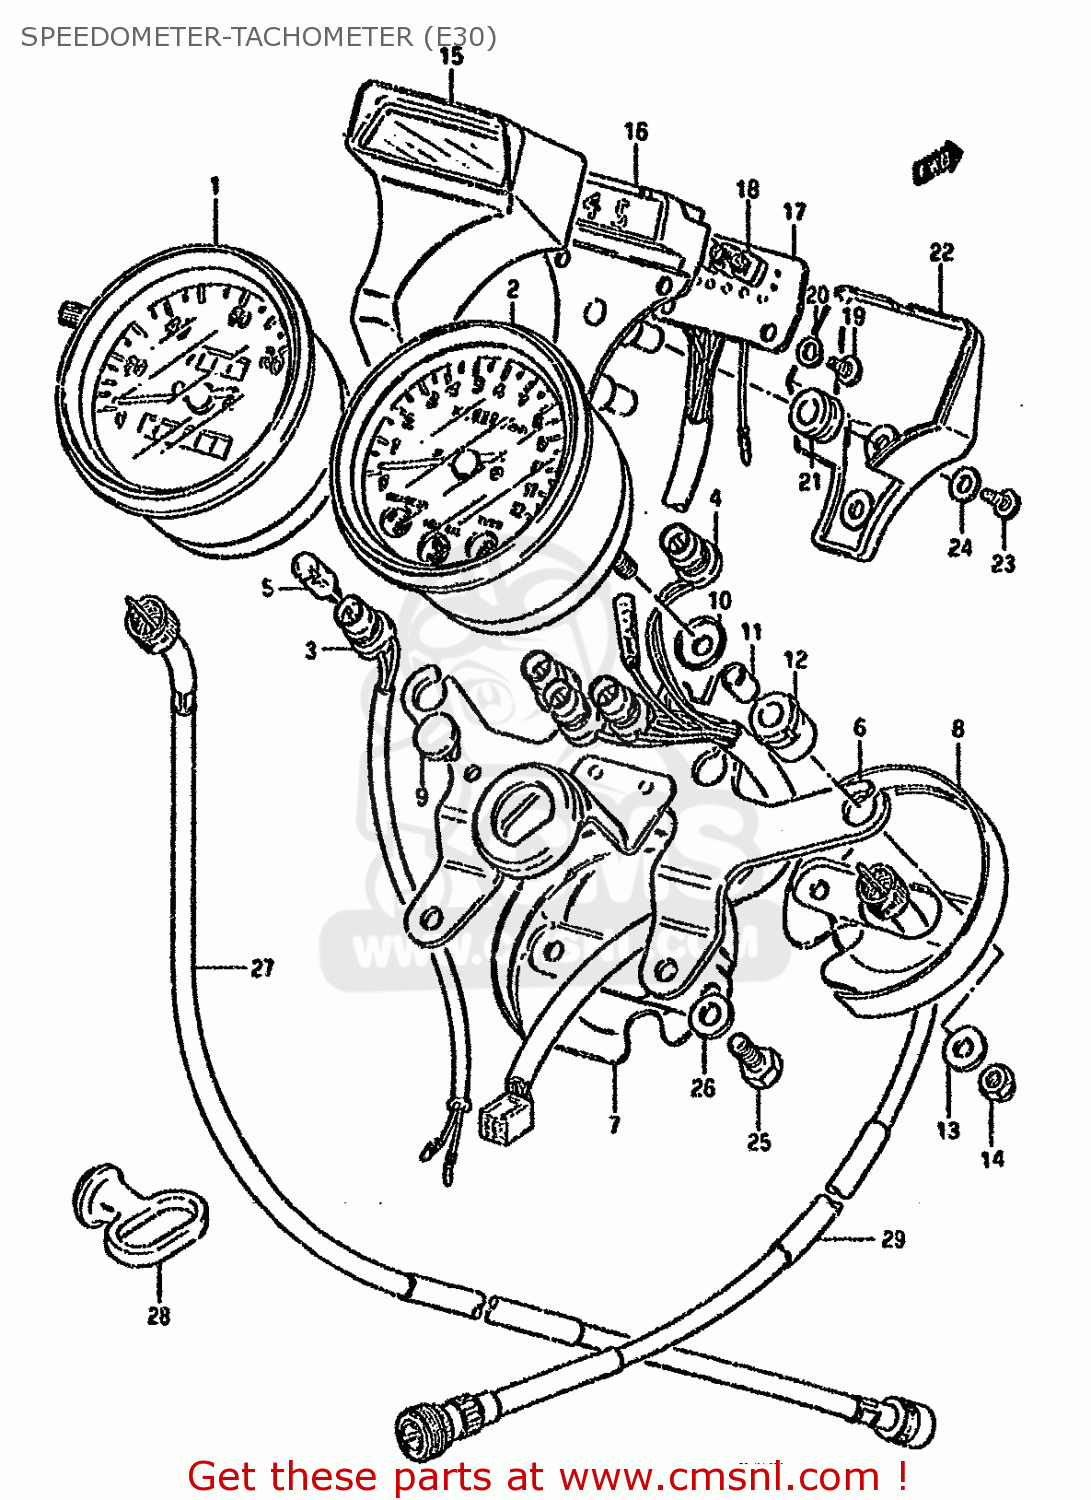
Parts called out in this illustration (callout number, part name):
1	SPEEDOMETER(KILO)
2	TACHOMETER
3	SOCKET,SPEEDOMETER
4	SOCKET,TACHOMETER
5	BULB(12V3.4W,T10,BF175-01450A)
6	BRACKET,METER
7	UNDER COVER,SPEEDOMETER
8	UNDER COVER,TACHOMETER
9	CUSHION,METER
10	WASHER
11	SPACER,SPEEDOMETER
12	CUSHION,METER
13	WASHER,METER
14	NUT
15	PILOT BOX
16	CASE,PILOT BOX
17	INDICATOR,GEAR POSITION
18	BULB(14V1.12W)
19	SCREW
20	WASHER,LOCK 4M
21	CUSHION
22	COVER,LWR
23	SCREW 4X16
24	WASHER
25	BOLT
26	WASHER
27	CABLE ASSY,SPEEDOMETER
28	GUIDE,CABLE
29	CABLE ASSY,TACHOMETER
